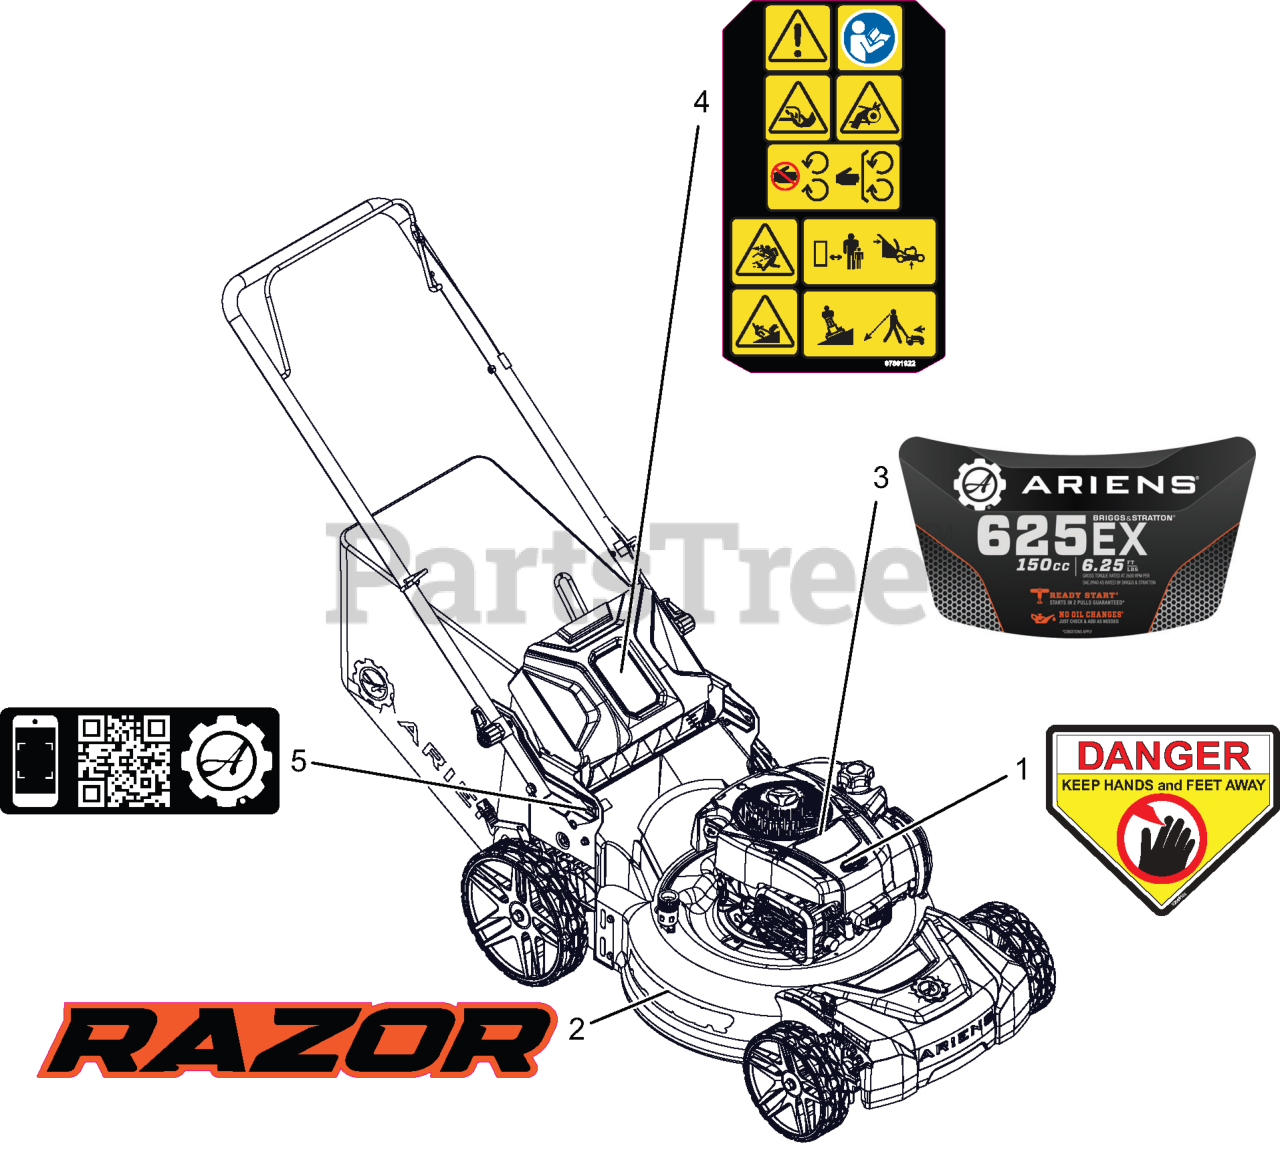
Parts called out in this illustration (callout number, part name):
1	DECAL, DANGER
2	DECAL, ARIENS RAZOR
3	DECAL, ENGINE 150CC
4	DECAL, MAIN SAFETY - WALK
5	DECAL, RAZOR QR
